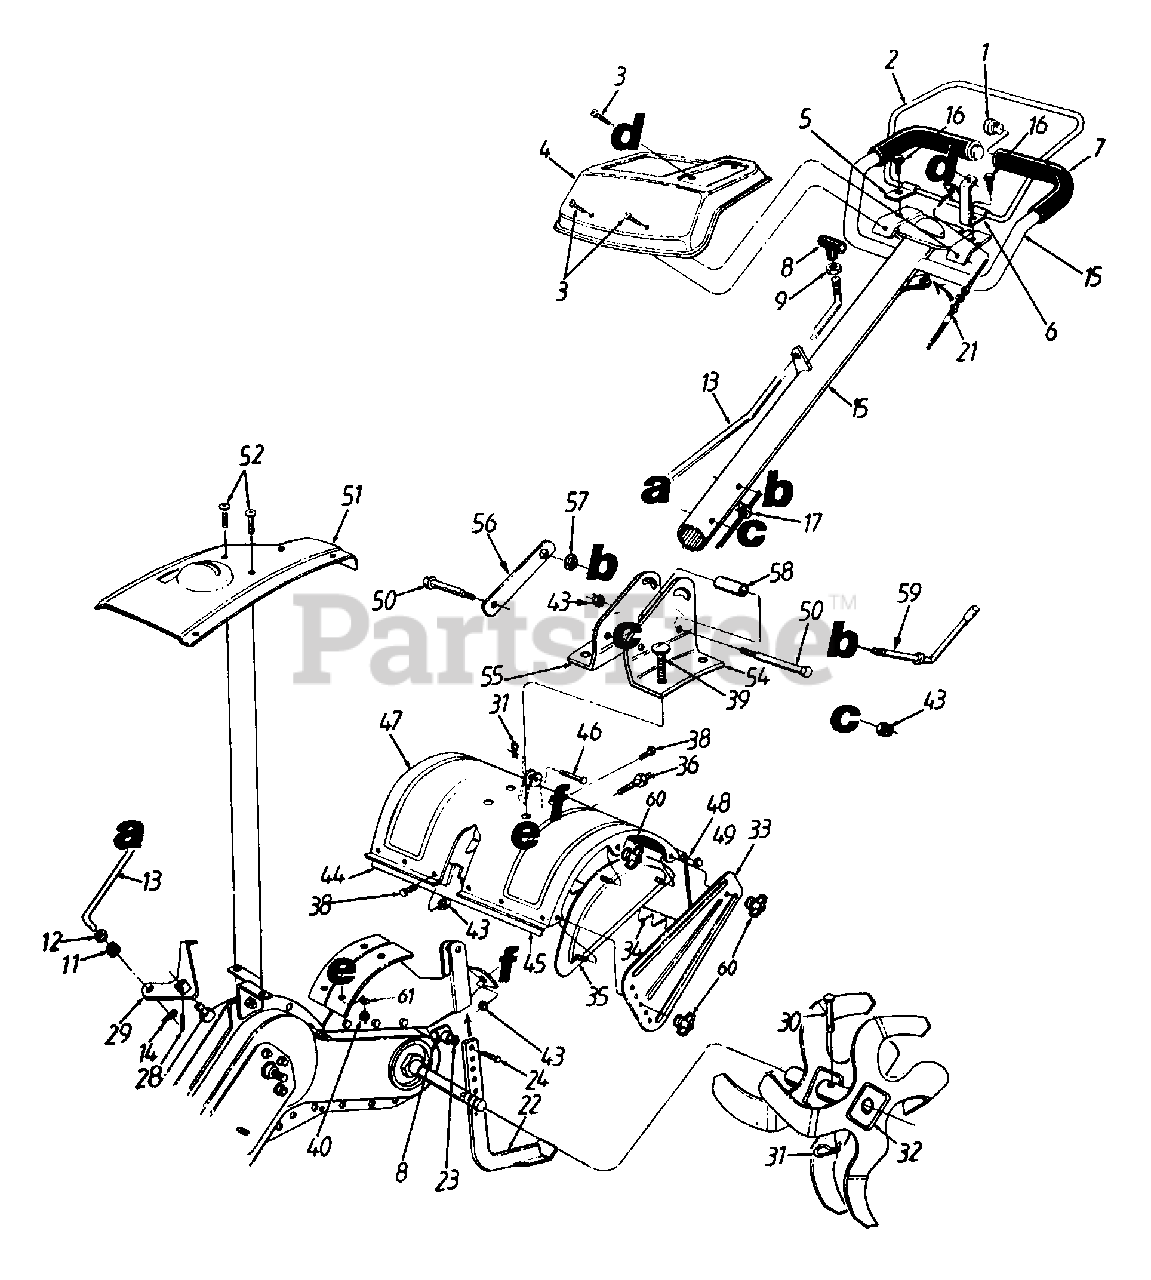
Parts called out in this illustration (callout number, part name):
1	Vinyl End Plug
3	Torx Mach. AB-Tap Scr. 1/4 x .62" Lg.
7	Grip (2 Req'd.)
9	Hex Jam Nut 3/8-16 Thd.
11	Rubber Washer
12	Fl-Wash. .344" I.D. x .6" O.D.
13	Gear Shift Rod
14	Hairpin Clip
17	Cable Clip
21	Clutch Cable
23	Fl-Wash. 3/8" I.D. x 5/8" O.D.
24	Hex Bolt 3/8-16 x 1" Lg.
28	Spiral Pin 3/16" x 1"
31	Hairpin Clip
36	Hex Cap Bolt 5/16-18 x 1.25"
38	Hex Bolt 5/16-18 x .75" Lg.
39	Carriage Bolt 3/8-16 x 1" Lg.
40	Hex Ins. L-Nut 3/8-16 Thd.
43	Hex Flange Top L-Nut 5/16-18 Thd.
46	Clevis Pin .375" Dia.
49	Cap Speed Nut
50	Hex Bolt 5/16-18 x 3" Lg.
57	Hex Flange Nut 3/8-24 Thd.
58	Spacer .322 Dia.
59	Handle Adjustment Crank
60	Knob 5/16-18 Thd.
61	L-Washer 3/8" I.D.
